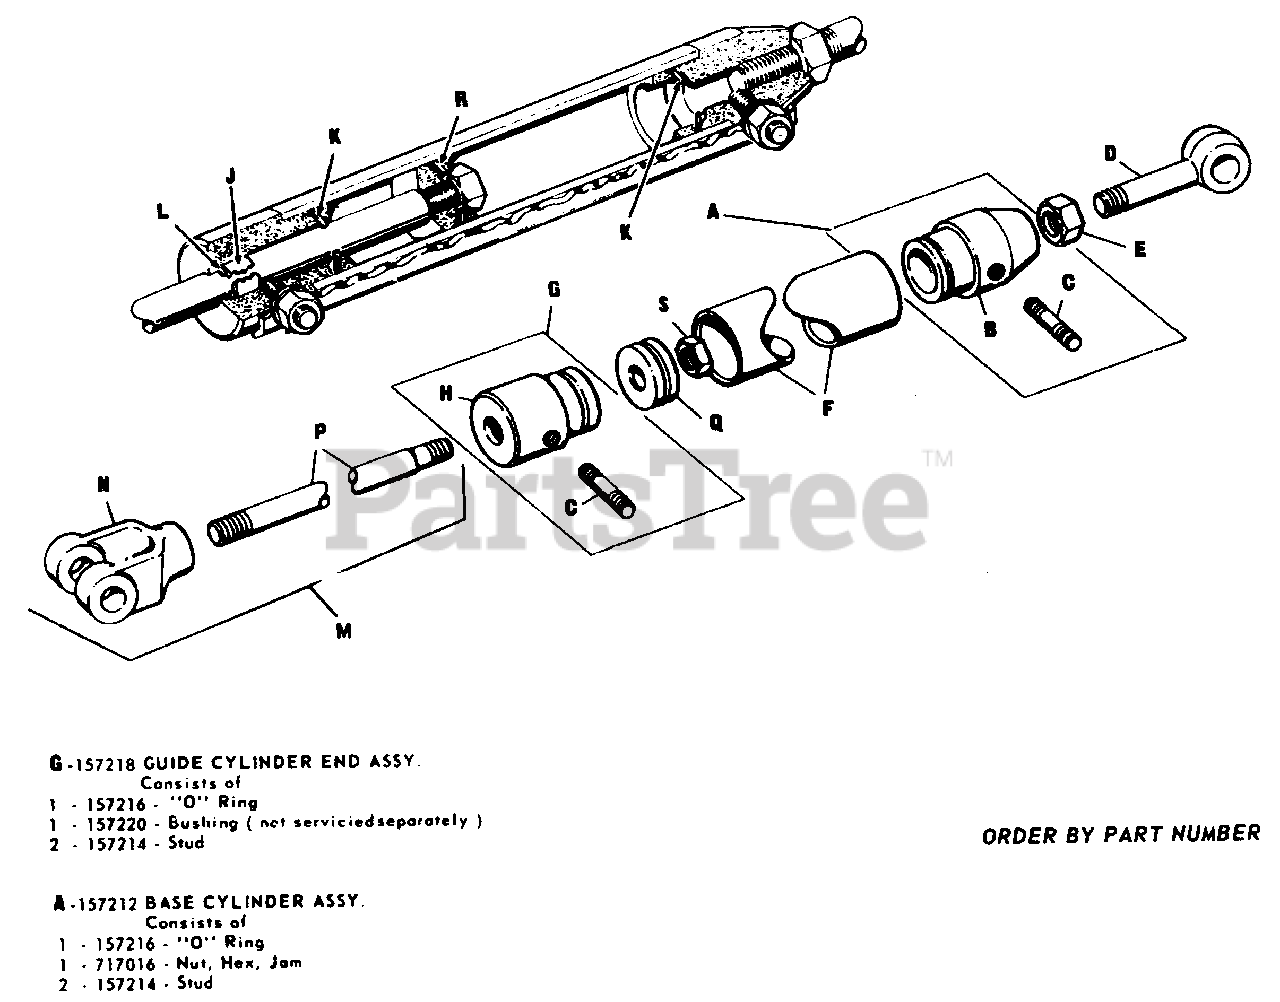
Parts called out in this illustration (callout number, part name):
A	Cylinder Base Sub-Assembly-Consists of:
A	"O" Ring
A	Nut, Hex Jam
A	Stud
B	Cylinder Base
C	Stud Bolt, 5/16"-18 x 7/8"
E	Jam Hex. Nut 1/2"-20
G	Sub Assembly Guide-Consists of:
G	"O" Ring
G	Bushing (not serviced separately)
G	Stud
H	Cylinder End Guide
M	Yoke & Rod Sub-Assembly
P	Piston Rod
S	Full Hex. Nut
